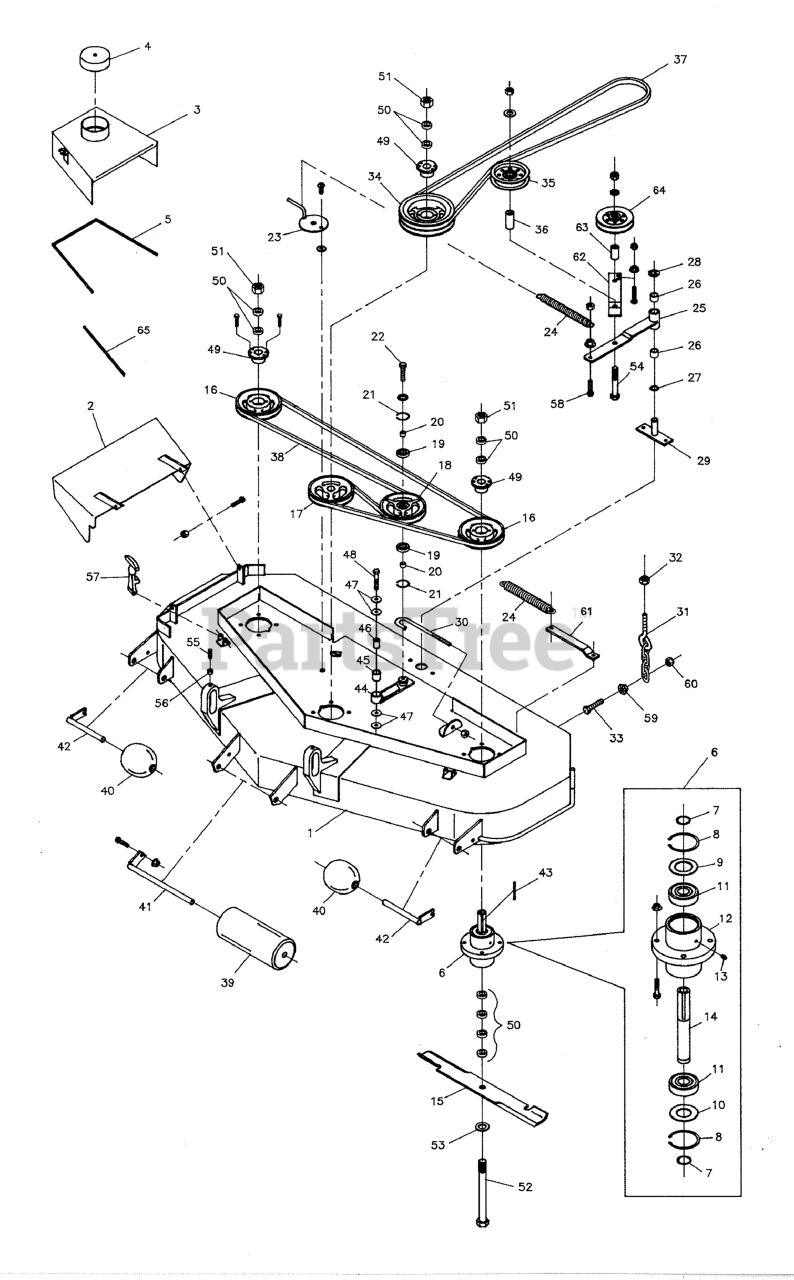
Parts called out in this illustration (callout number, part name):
1	61" MOWER HOUSING
2	DISCHARGE CHUTE
3	Deck Guard - RH
4	VINYL CAP
5	Body Molding
6	SPINDLE ASSEMBLY, Complete
7	SNAP RING, External
8	SNAP RING, Internal
9	SPINDLE WASHER, Top
10	SPINDLE WASHER, Bottom
11	BEARING
12	SPINDLE HOUSING
13	GREASE FITTING
14	SPINDLE SHAFT
15	MOWER BLADE, 21"
16	PULLEY, Spindle
17	SPINDLE PULLEY
18	IDLER PULLEY, Complete
18	PULLEY, Idler
19	BEARING, BALL 11/16X1-9/16X15/32
20	INSERT, Bearing
21	SNAP RING, Internal
22	BOLT, 1/2-20 X 1-3/4" GD8 CZ
23	Spring Tension Base
24	SPRING, Extension
25	Tension Arm Weldment
26	BUSHING, Brass
27	SHIM
28	C-CLIP
29	Tension Pivot
31	Deck Chain Weldment
32	Height Adjustment Nut
33	BOLT, 7/16-14 x 2, TFL
34	Double Pulley
35	PULLEY, Backside Idler
36	SPACER, .50 x 1.00 x 2.25
37	Belt - Engine #10 Deck
38	BELT, Blade Spindle
39	ROLLER
40	Small Roller
42	Small Roller Pin
43	KEY, 1/4 SQ. X 2-1/2
44	IDLER ARM
45	BUSHING, Brass
46	SPACER, .32 x .75 x 1.06
47	WASHER, 5/16" Fender
48	BOLT, 5/16-18 X 2
49	BUSHING, Tapered Hub
50	SPACER, .63 x 1.06 x .23
51	NUT, 5/8-11 Hex
52	BOLT, 5/8-11 x 9-1/2
53	WASHER, 5/8" USS
54	BOLT, 1/2-13 X 4" GD5 CZ
55	SET SCREW, 3/8-16 x 1-1/4"
56	NUT, 3/8-16 Hex
57	RUBBER LATCH
58	BOLT, 5/16-18 x 1-1/4
59	NUT, 7/16-14 Hex Serrated Flange
60	NUT, 7/16-14 Hex Nylon Lock
61	Spring Anchor
62	Rocker Arm
63	Rocker Arm Pivot
64	Idler Pulley
65	Body Molding
